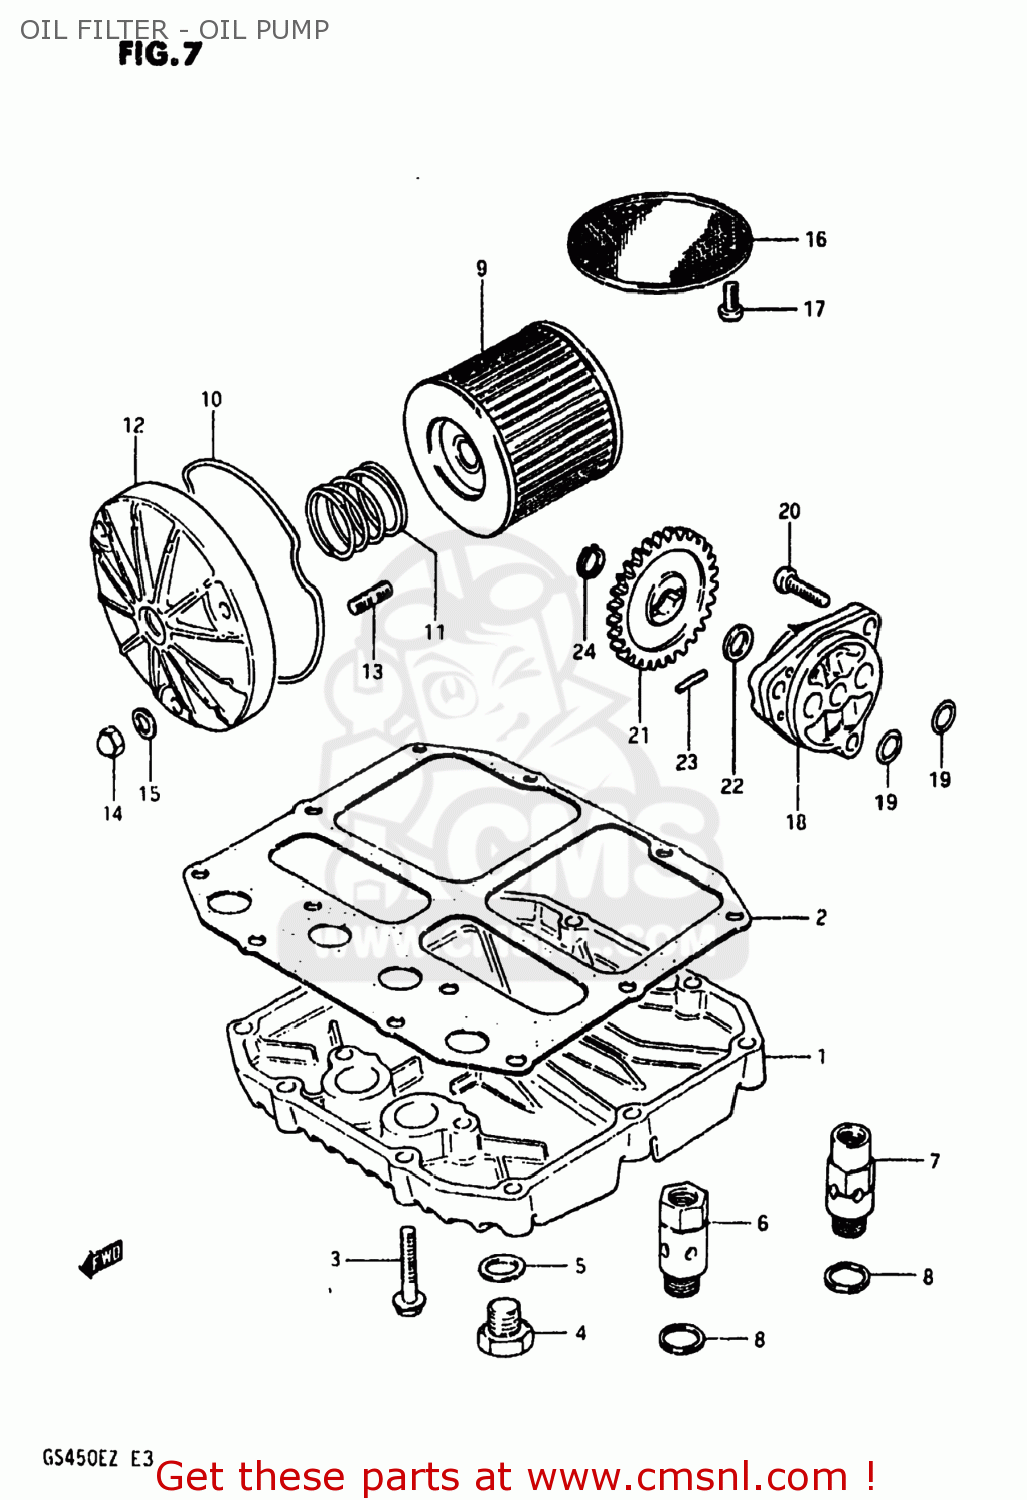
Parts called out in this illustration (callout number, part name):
1	PAN,OIL
2	GASKET,OIL PAN (MCA)
3	BOLT
4	PLUG
5	GASKET(14X19.2X2) (NAS)
6	REGULATOR ASSEMBLY,ENGINE
7	REGULATOR ASSEMBLY,ENGINE
8	WASHER
9	FILTER ASSY,ENGINE OIL
10	O RING,OIL FILTER CHAMBER CAP
11	SPRING
12	CAP,OIL FILTER
13	STUD 6X20
14	NUT
15	WASHER
16	STRAINER,ENGINE OIL
17	SCREW 6X12
18	PUMP ASSY,ENGINE OIL
19	O RING(D:1.9,ID:13)
20	SCREW
21	GEAR,OIL PUMP DRIVEN
22	SHIM
23	PIN(4X15.8)
24	CIRCLIP
